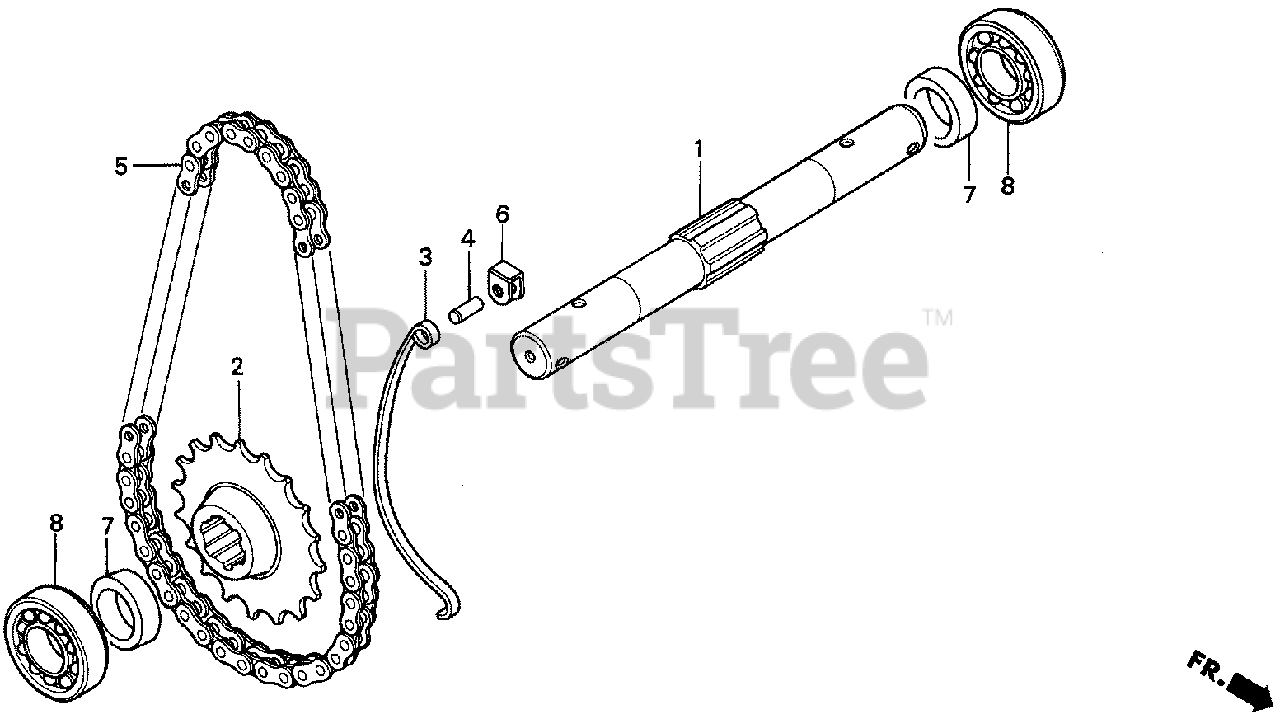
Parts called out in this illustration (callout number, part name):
1	SHAFT, WHEEL
2	SPROCKET, DRIVEN
3	TENSIONER, CHAIN (NOT AVAILABLE)
4	SHAFT, TENSIONER (NOT AVAILABLE)
4	SHAFT, TENSIONER
5	CHAIN, FINAL
6	SPACER, CHAIN TENSIONER
7	COLLAR, WHEEL SHAFT
8	BEARING, RADIAL BALL (6007)
